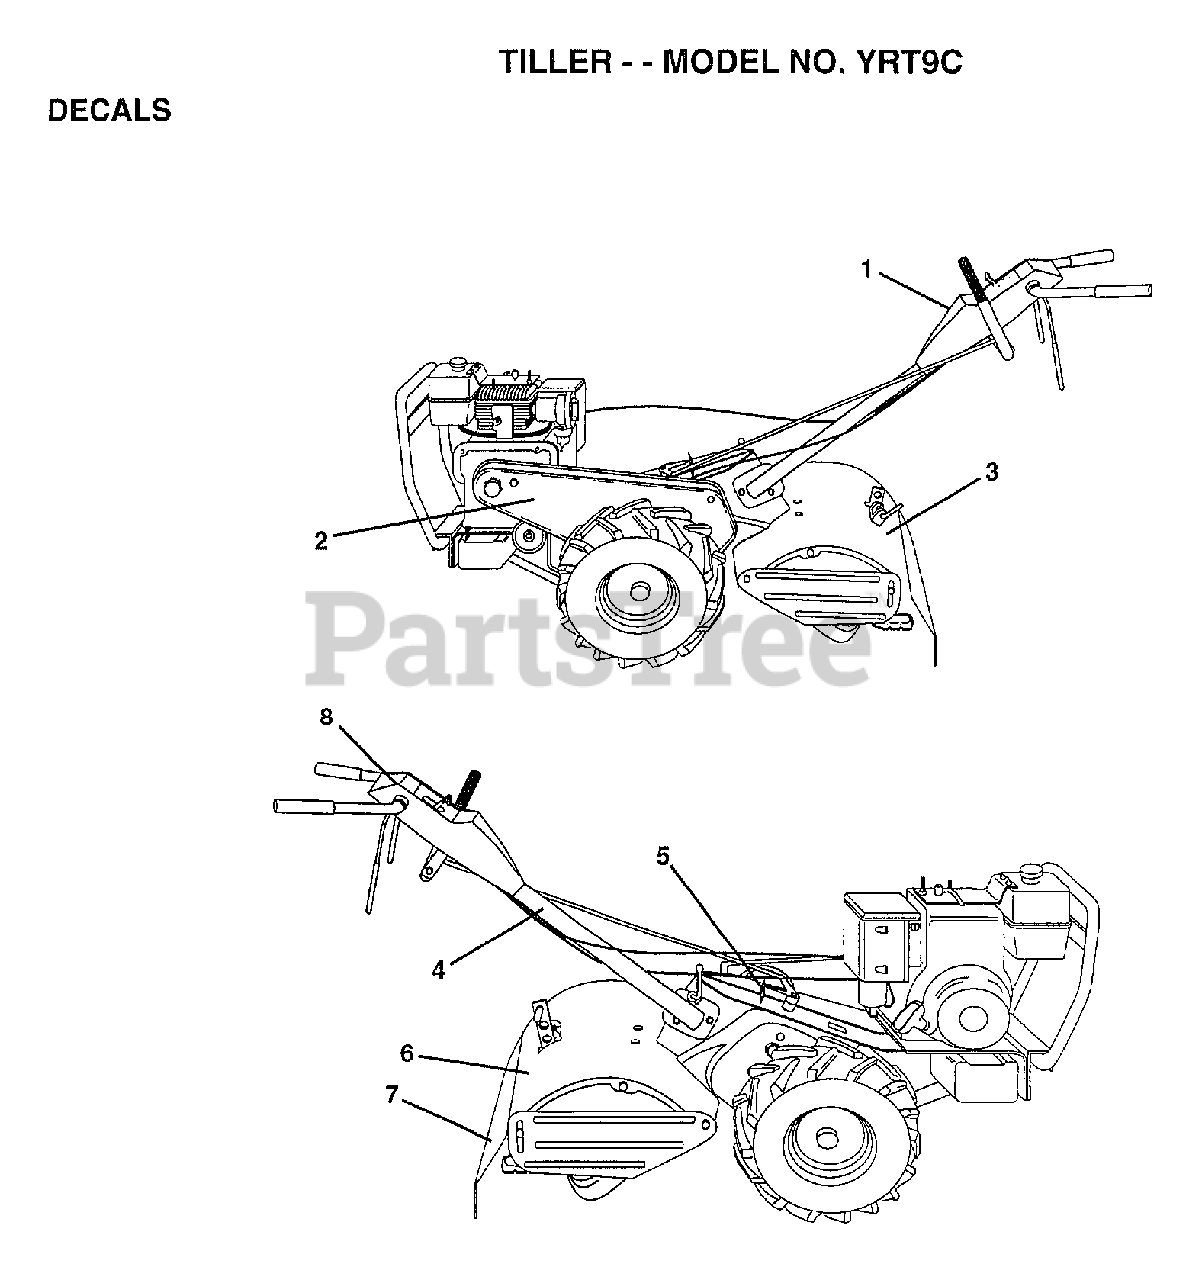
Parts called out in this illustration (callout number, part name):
1	DECAL PANEL CNTRL
2	DECAL GUARD BELT
3	DECAL SHIELD TINE
4	DECAL TI
5	DECAL.SHIFT.IND.
6	DECAL.CAUTION
8	DECAL INST PNL 21
